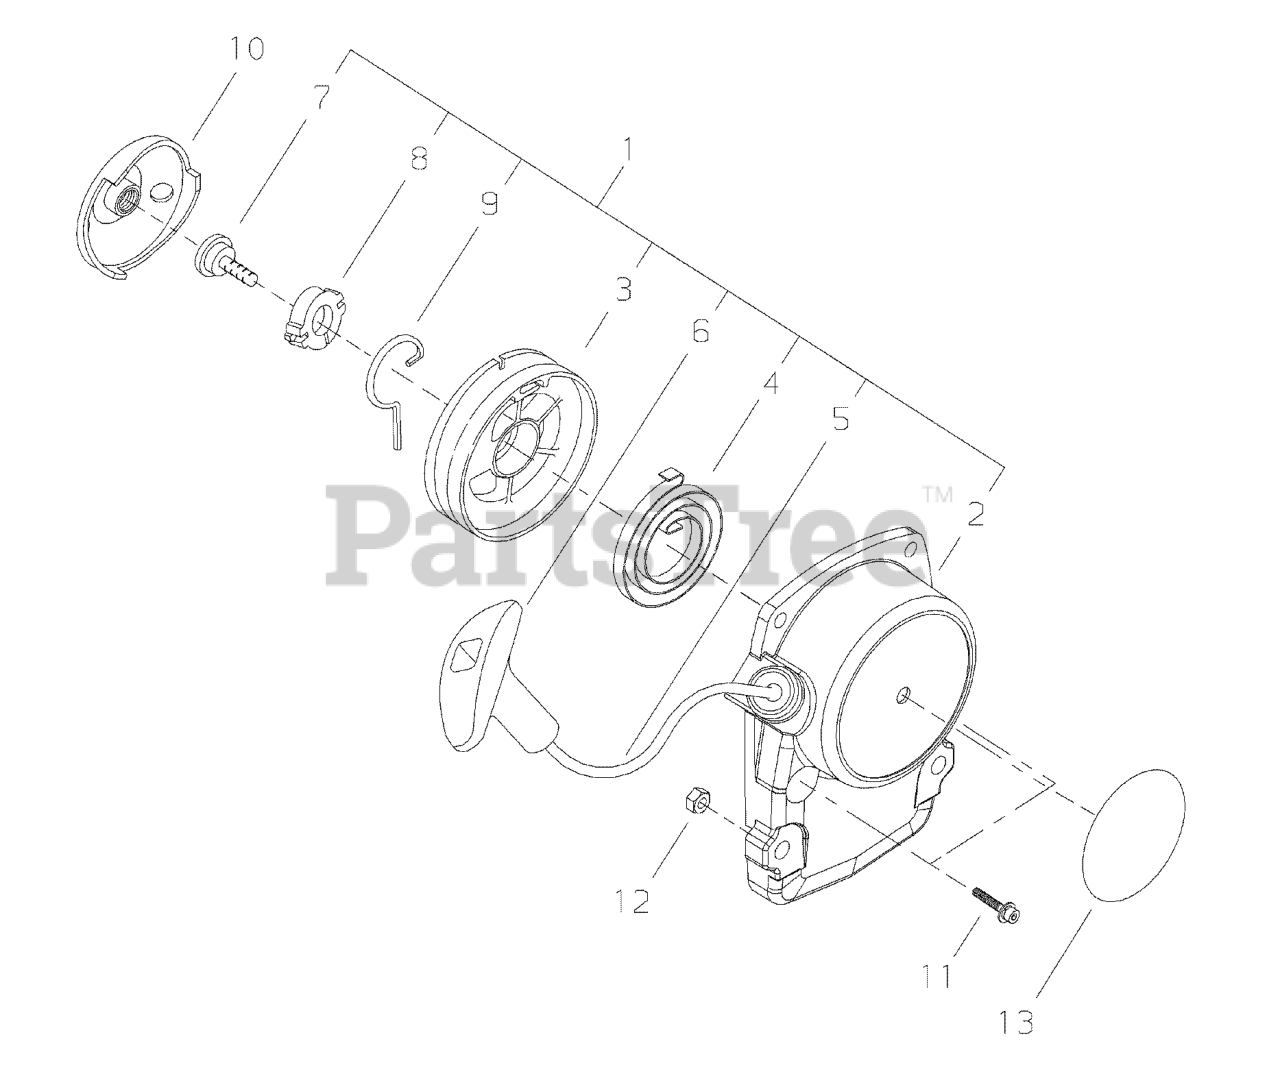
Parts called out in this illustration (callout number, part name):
1	STARTER ASSY
2	CASE, STARTER
3	REEL, ROPE
4	SPRING, REWIND
5	ROPE, STARTER
6	GRIP, STARTER
7	SCREW - 5
8	WASHER - 5
9	PAWL, STARTER
10	STARTER PAWL ASSY
11	SCREW - 4X16
13	LABEL - SHINDAIWA
